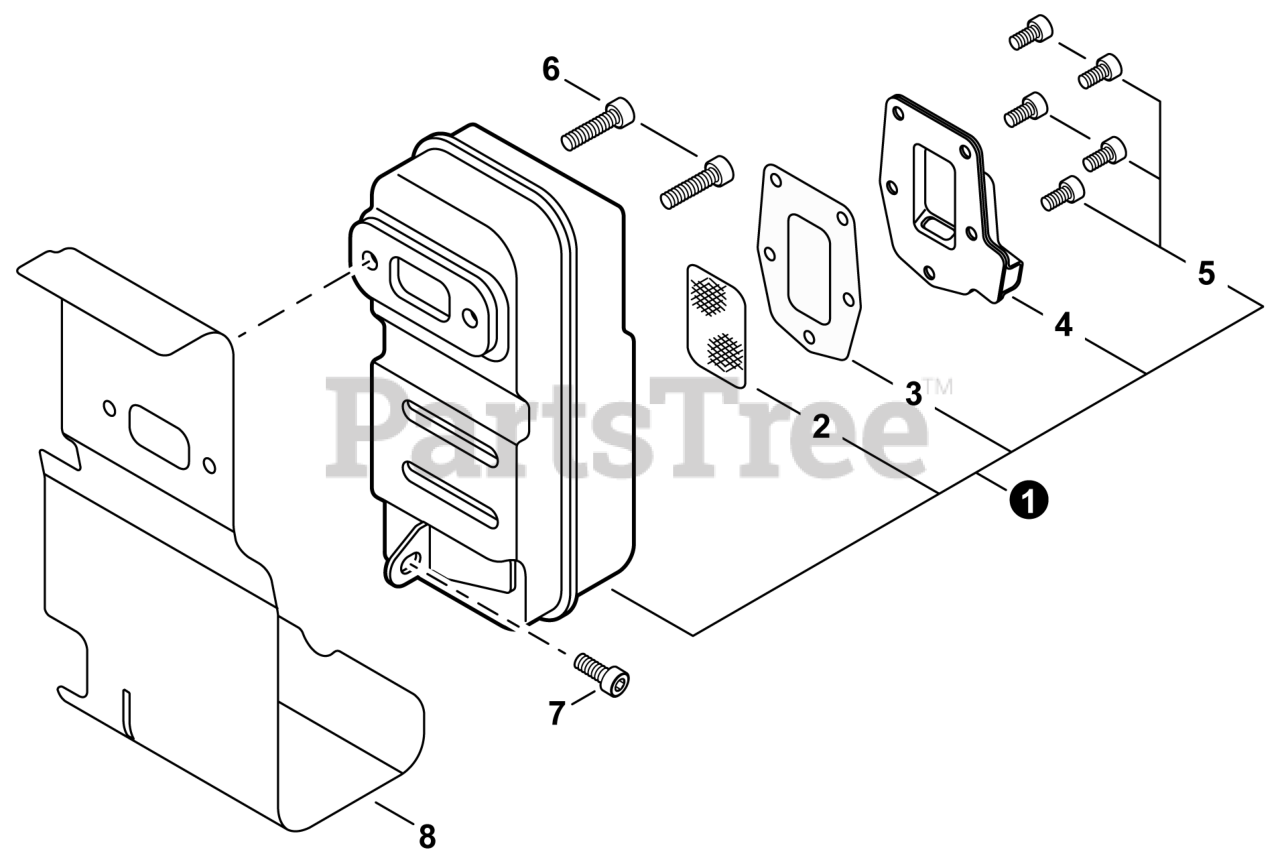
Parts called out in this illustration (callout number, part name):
1	MUFFLER ASSY
2	SCREEN, SPARK ARRESTER
3	GASKET, EXHAUST
4	GUIDE, EXHAUST
5	BOLT, TORX 4x10
6	BOLT 6x20
7	BOLT, TORX 5x16
8	HEAT SHIELD, EXHAUST
